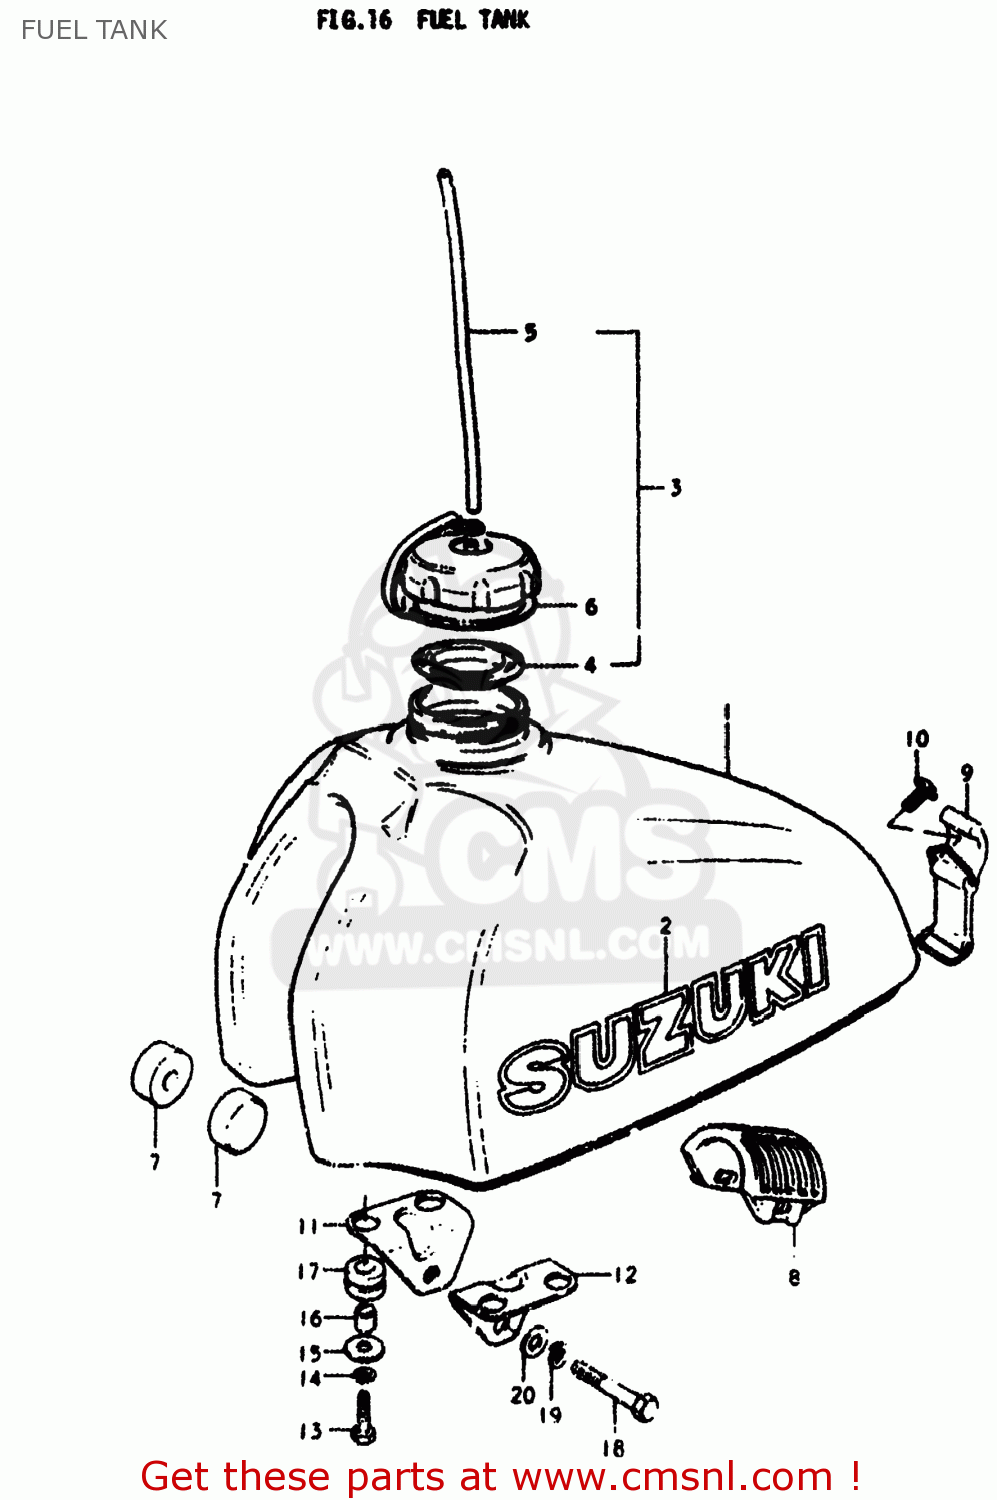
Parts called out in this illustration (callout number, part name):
1	TANK ASSEMBLY,FUEL
2	EMBLEM(BLACK)
3	CAP ASSY,FUEL TANK
4	GASKET,FUEL TANK CAP (NAS)
5	HOSE
6	BAND,FUEL TANK CAP
7	CUSHION
8	CUSHION,FUEL TANK
9	BAND
10	SCREW(6X18)
11	BRACKET,FUEL TANK
12	BRACKET,FUEL TANK
13	BOLT
14	LOCK WASHER
15	WASHER (6.5X20X1.2)
16	SPACER (6.8X10X10)
17	CUSHION
18	BOLT
19	LOCK WASHER
20	WASHER
